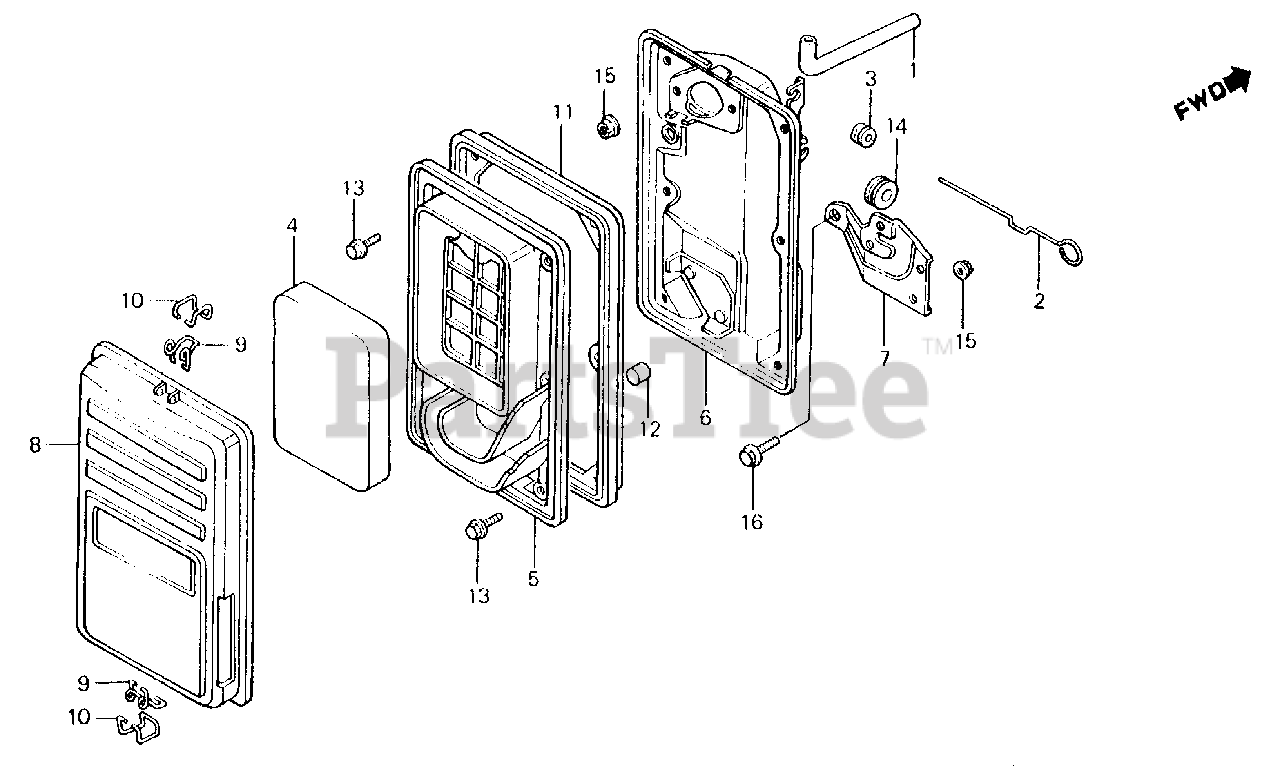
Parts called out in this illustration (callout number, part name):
1	TUBE, BREATHER
2	ROD, CHOKE CONTROL
3	GROMMET, CHOKE ROD
4	ELEMENT, AIR CLEANER
5	SEPARATOR, AIR CLEANER
6	HOUSING, AIR CLEANER (NOT AVAILABLE)
7	STAY, AIR CLEANER
8	COVER, AIR CLEANER
9	CLIP A, AIR CLEANER WIRE
10	CLIP B, AIR CLEANER WIRE
11	SEAL, AIR CLEANER
12	FILTER, DRAIN TUBE
13	BOLT, SETTING
14	RUBBER, CONTROL BOX
15	NUT, FLANGE (6MM)
16	BOLT, FLANGE (8X16)
